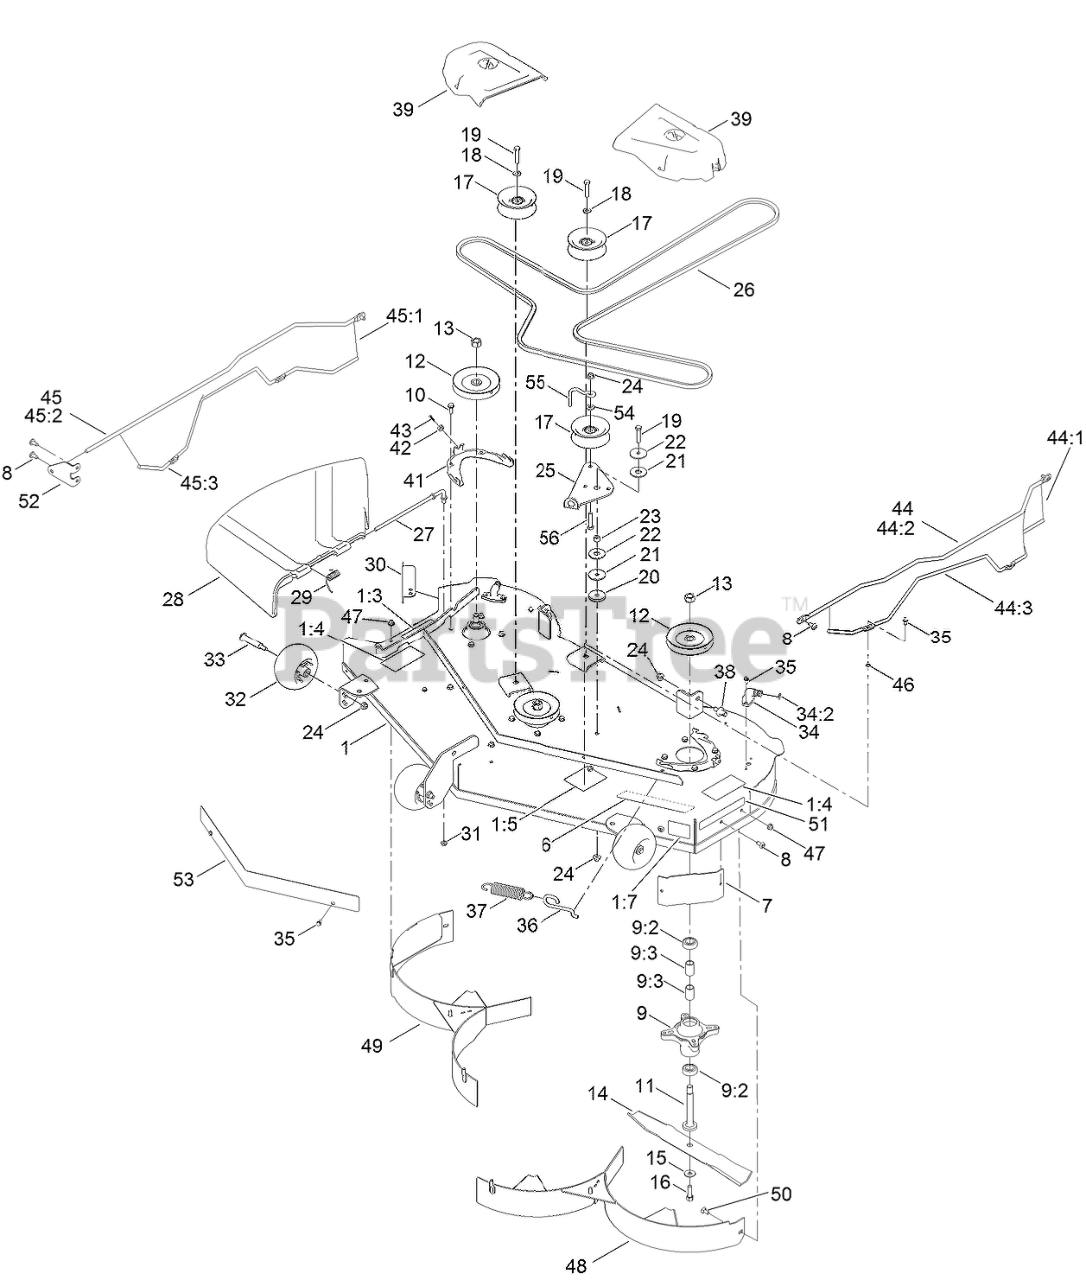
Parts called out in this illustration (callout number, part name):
1	50 INCH DECK AND DECAL ASM
1:3	DECAL-DANGER
1:4	DECAL-DANGER, DECK
1:5	DECAL-ROUTING, BELT
1:7	DECAL-SCALP, ANTI
6	DECAL - DECK
7	BAFFLE-CORNER
9	SPINDLE ASM
9:2	SPACER
9:3	BEARING-BALL
10	SCREW-TAPTITE
11	SHAFT-SPINDLE
12	PULLEY
13	Nut-Hex
14	BLADE-MULCH, 17.50 INCH
15	WASHER-BELLEVILLE
16	SCREW-HH
17	PULLEY-IDLER, FLAT
18	WASHER-FLAT
19	SCREW-HH
20	WASHER-PLAIN
21	Washer
22	WASHER-FRICTION, COMPOSITE
23	SPACER
24	NUT-HF, NI
25	ARM-IDLER
26	V-BELT
27	ROD-PIVOT
28	DEFLECTOR-DISCHARGE
29	SPRING-TORSION
30	BAFFLE-CUTOFF
31	NUT-HEX
32	ROLLER-SCALP, ANTI
33	BOLT-SHOULDER
34	FITTING-WASHOUT
34:2	O-RING
35	SCREW-HWH
36	HOOK-RETURN SPRING
37	SPRING-EXTENSION
38	PIN-DECK
39	COVER-BELT
41	BRACKET-COVER, BELT
42	SPACER-NOTCHED
43	SCREW-PPH
44	LEFT GUARD ASM
44:2	ROD-TOP, LEFT
44:3	ROD-SUPPORT, LOWER
45	RIGHT GUARD ASM
45:2	ROD-TOP, RIGHT
45:3	ROD-SUPPORT, LOWER
46	NUT-RETAINING
47	NUT-HF
48	50IN BAFFLE ASM
49	50IN BAFFLE ASM
50	BOLT-CARR
51	DECAL-RECYCLER
52	PLATE-MOUNT, GUARD
53	SHIELD-FRONT
54	SPACER-HUB, BLOWER
55	BELT GUIDE - IDLER
56	SCREW-HH
